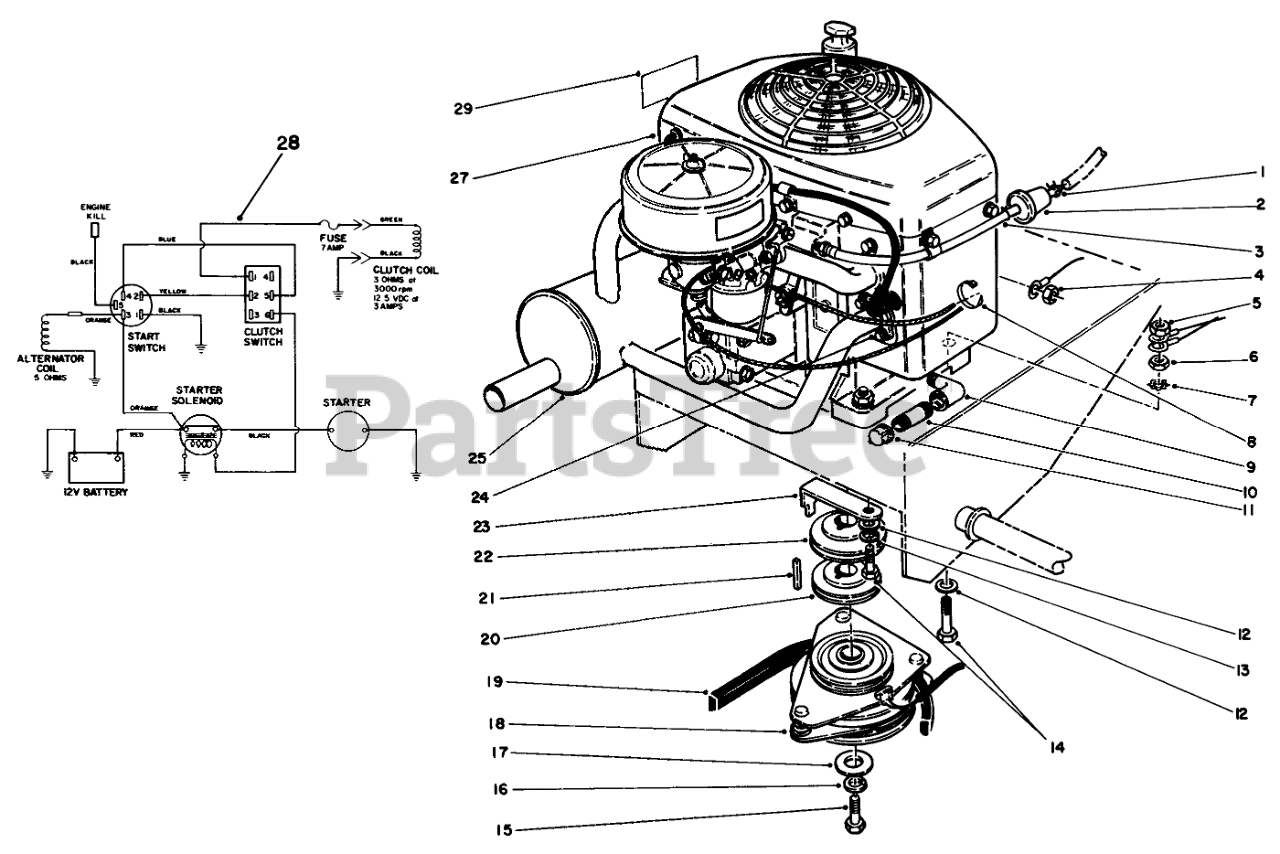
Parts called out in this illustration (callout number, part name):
1	CLAMP-HOSE
2	Fuel-Filter
3	Hose-Gas
4	NUT-KEPS
5	NUT-KEPS
6	NUT-LOCK, CONE
7	WASHER-LOCK
8	TIE-CABLE
9	ELBOW-STREET, 90 DEG
10	NIPPLE
11	CAP-PIPE
12	WASHER-PLAIN
13	WASHER-LOCK
14	SCREW-HH
15	SCREW-HH
16	WASHER-LOCK
17	WASHER-CLUTCH
18	CLUTCH/BRAKE
19	V-BELT, DRIVE
20	SHEAVE-LOWER HALF
21	KEY-SQUARE
22	SHEAVE-UPPER HALF
23	Retainer-Clutch
24	SCREW-HSH
25	Muffler
26	EXHAUST GASKET F/W ENG.
28	16 HP WIRING HARNESS
29	DECAL-SURFACE, HOT
